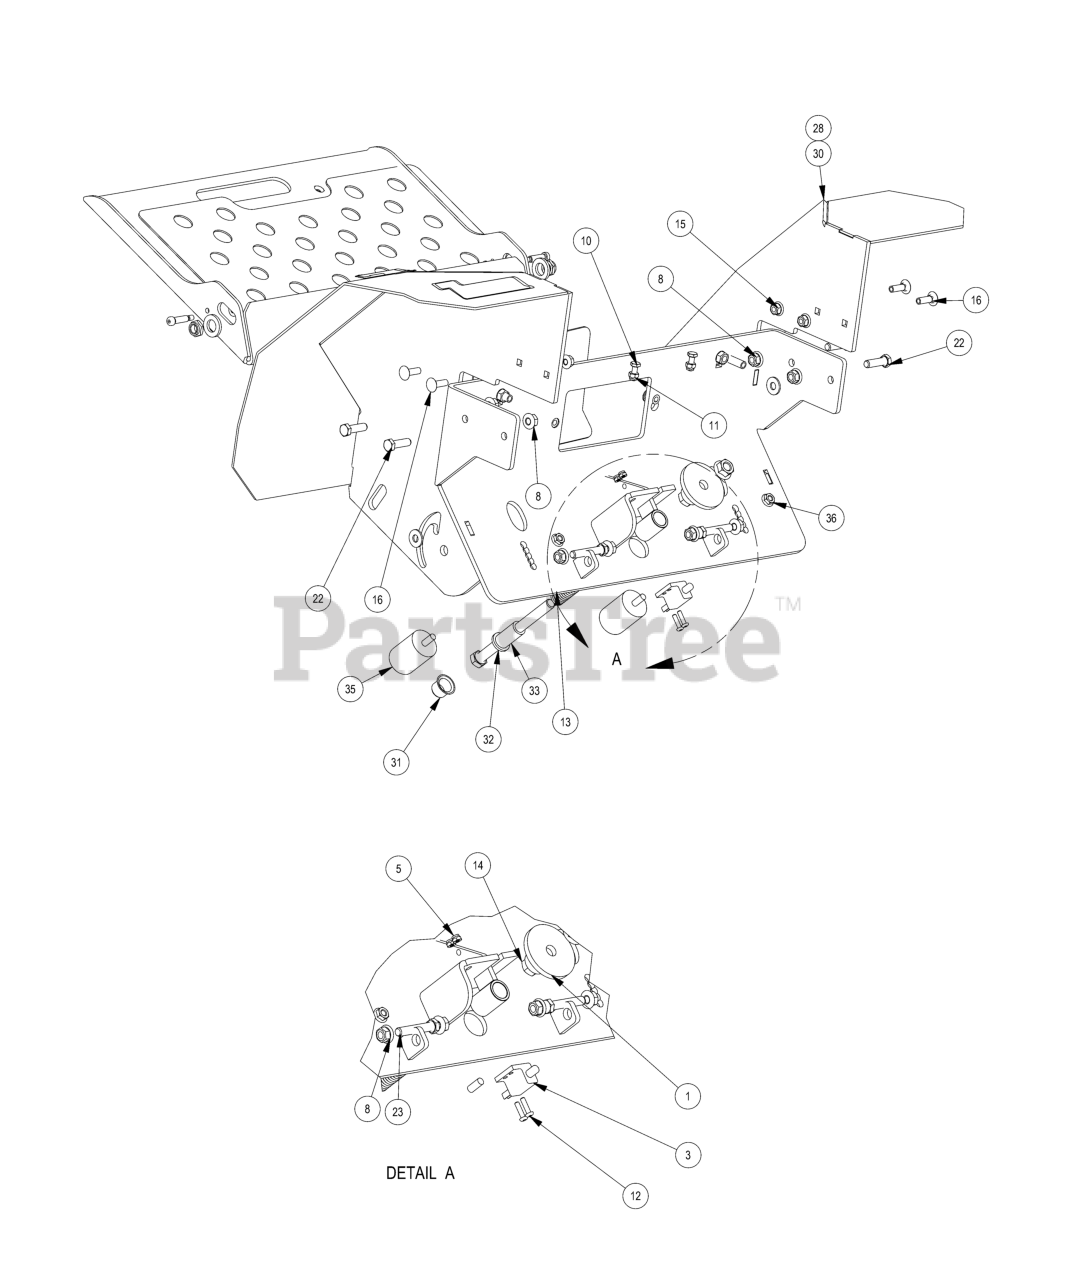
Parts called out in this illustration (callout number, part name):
1	MZ Deck Idler Spacer
2	1/4"-20 x 3/4" Knurled Thumb Screw
3	safety Switch
4	2019 Stand On Access Panel Plate Black Part
5	10-24 NYLON INSERT LOCKNUT ZINC
6	5/16 USS FLAT WASHER (7/8 OD) ZINC
7	3326 Wellnut (1/4-20 x 5/18")
8	3/8-16 NYLON INSERT FLANGE LOCKNUT (GR.F) ZINC
9	3/8-16 X 1-1/4 CARRIAGE BOLT ZINC
10	1/4-20 X 3/4 HEX CAP SCREW (GR.5) ZINC
11	1/4-20 NYLON INSERT LOCKNUT ZINC
12	10-24 X 3/4 BUTTON SOCKET CAP SCREW 18-8 STAINLESS
13	Rider Presence Spring 9657K145
14	1/2-13 HEX SERRATED FLANGE NUT HARD/ZINC
15	5/16-18 NYLON INSERT FLANGE LOCKNUT ZINC
16	5/16-18 X 1 CARRIAGE BOLT (GR.8) ZINC
17	Steel Shoulder Screw 1/4"-20 x 7/8" Diameter 5/16"
18	1/4-20 HEX SERRATED FLANGE NUT HARD/ZINC
19	5/8 X 5/8 SOCKET SHOULDER BOLT ZINC YELLOW
20	.635 ID X 1.120 OD X .140 THICK FLAT WASHER NYLON
21	1/2-13 NYLON INSERT JAM LOCKNUT ZINC
22	3/8-16 X 1-1/4 HEX CAP SCREW (GR.5) ZINC
23	3/8-16 X 2 HEX CAP SCREW (GR.5) ZINC
27	Grip Tape for 026-0062-00
28	2023 Platform Support 61 weldment
29	2023 Platform_2
30	2023 Platform Support 54/48
31	Hex Nut Cap
32	1/2-13 X 6 HEX CAP SCREW (GR.5) ZINC
33	.504 ID X .740 OD X 1.625 LGTH SLEEVE WASHER NYLON
35	Revolt Bumper
36	5/16-18 HEX SERRATED FLANGE NUT HARD/ZINC
